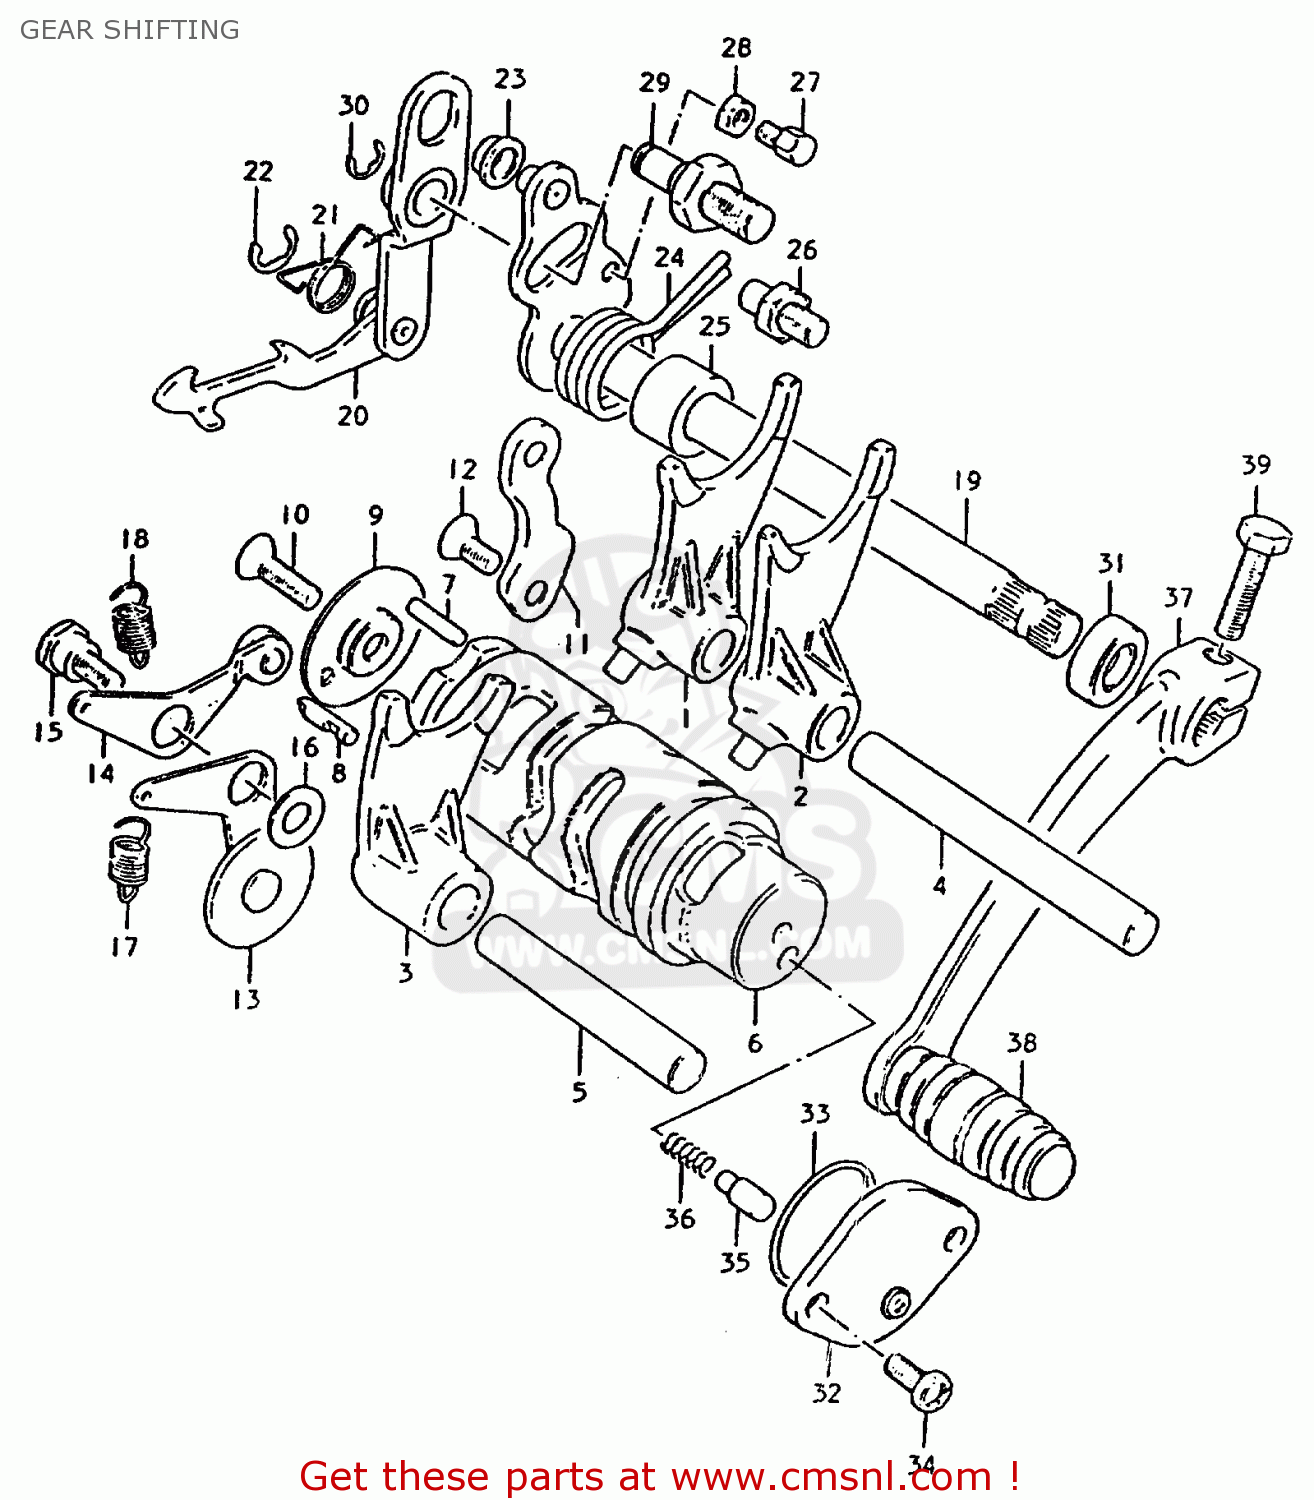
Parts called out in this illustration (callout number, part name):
1	FORK,GEAR SHIFT NO.1
2	FORK,GEAR SHIFT NO.2
3	FORK,GEAR SHIFT NO.2
4	SHAFT,GEAR SHIFT FORK
5	SHAFT,GEAR SHIFT FORK
6	CAM,GEAR SHIFT
7	PIN(4X15.8)
8	PIN
9	RETAINER,GEAR SHIFT CAM DR PIN
10	SCREW
11	GUIDE,GEAR SHIFT CAM
12	SCREW
13	STOPPER,GEAR SHIFT CAM
14	STOPPER,GEAR SHIFT CAM NEUTRAL
15	BOLT(6X18.3)
16	WASHER
17	SPRING
18	SPRING
19	SHAFT, GEAR SHIFTING
20	PAWL,GEAR SHIFT
21	SPRING
22	E RING
23	SPACER(7X10X5)
24	SPRING
25	SPACER(12X20X15.3)
26	STOPPER,GEAR SHIFT CAM
27	BOLT,GEAR SHAFT RETURN SPR SET
28	NUT 6MM
29	STOPPER,GEAR SHIFT CAM
30	E RING 6MM
31	OIL SEAL
32	BODY,GEAR SHIFT SWITCH
33	O-RING (D:2.4 ID:26.2)
34	SCREW
35	PIN(5X15.5)
36	SPRING
37	LEVER ASSY,GEA
38	RUBBER,GEAR SHIFT PEDAL
39	BOLT
